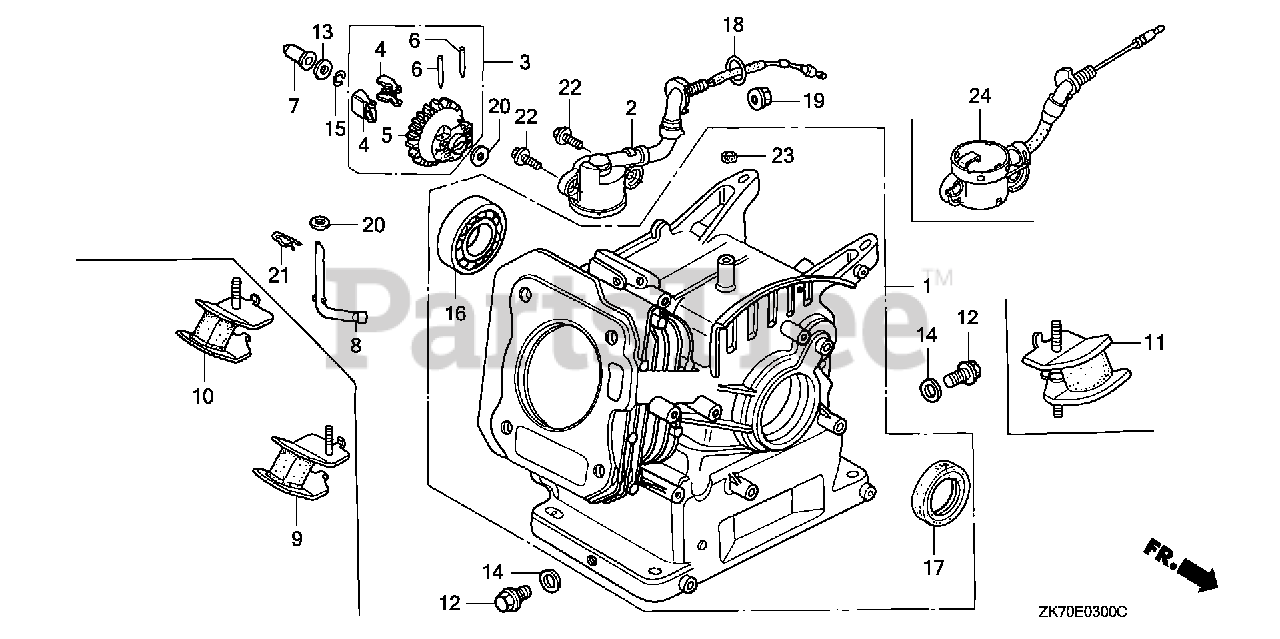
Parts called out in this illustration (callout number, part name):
1	CYLINDER ASSY.
2	SWITCH ASSY., OIL LEVEL
3	GOVERNOR ASSY.
4	WEIGHT, GOVERNOR
5	HOLDER, GOVERNOR WEIGHT
6	PIN, GOVERNOR WEIGHT
7	SLIDER, GOVERNOR
8	SHAFT, GOVERNOR ARM
12	BOLT, DRAIN PLUG
13	WASHER, THRUST (6MM)
14	WASHER, DRAIN PLUG (10.2MM)
15	CLIP, GOVERNOR HOLDER
16	BEARING, RADIAL BALL (62/22)
17	OIL SEAL (22X35X6)
18	O-RING (14MM) (ARAI) Use up to Engine SN 2949254.
18	O-RING (14MM) (NOK)
19	NUT, FLANGE (10MM)
20	WASHER, PLAIN (6MM)
21	PIN, LOCK (8MM)
22	BOLT, FLANGE (6X12) Use up to Engine SN 1543277.
24	SWITCH ASSY., OIL LEVEL
